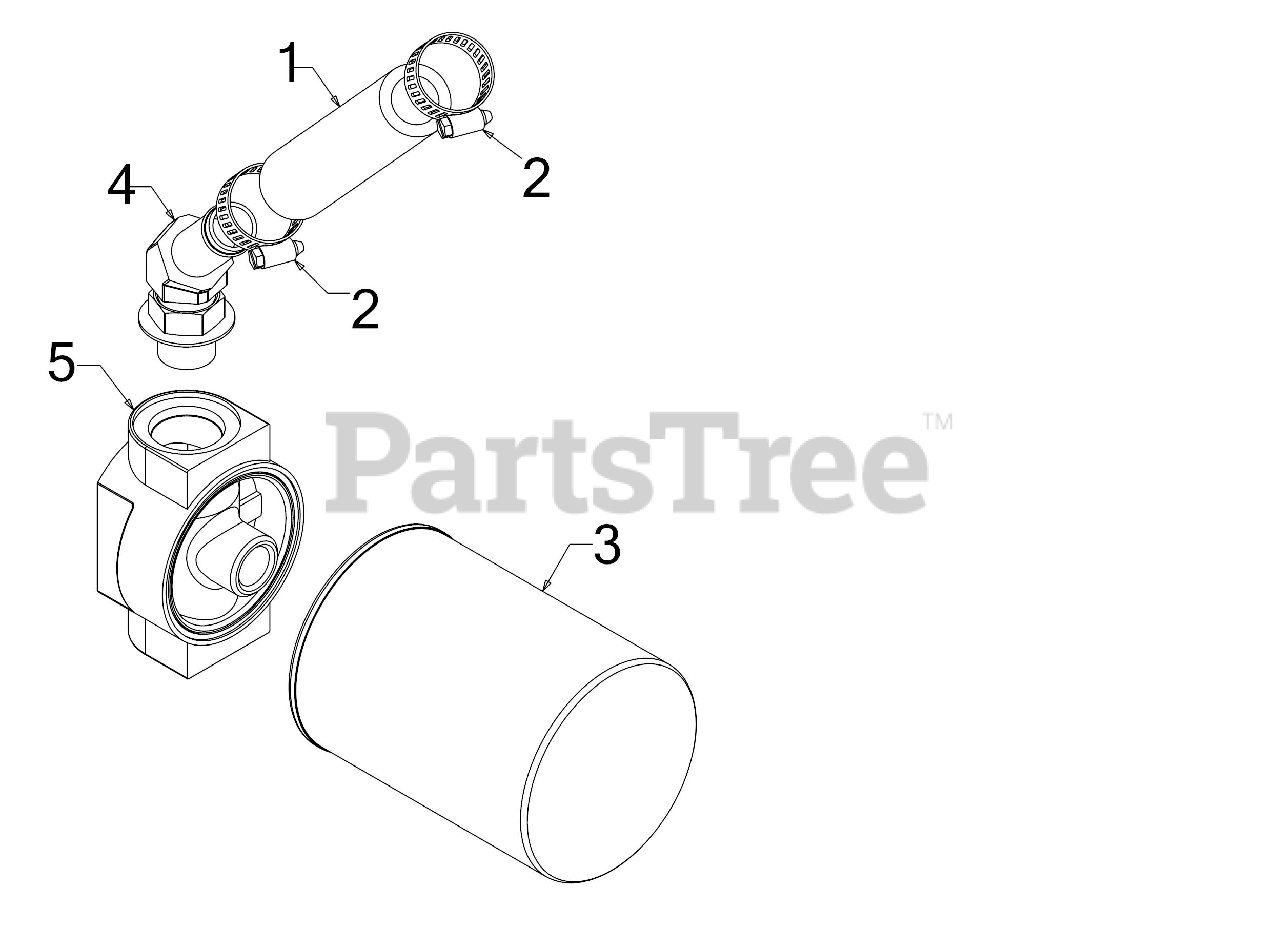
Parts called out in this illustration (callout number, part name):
1	RETURN HOSE
2	HOSE CLAMP-5/8
3	OIL FILTER
4	HYDRAULIC FITTING1 1/16 ORB x .75
5	FILTER HOUSING
